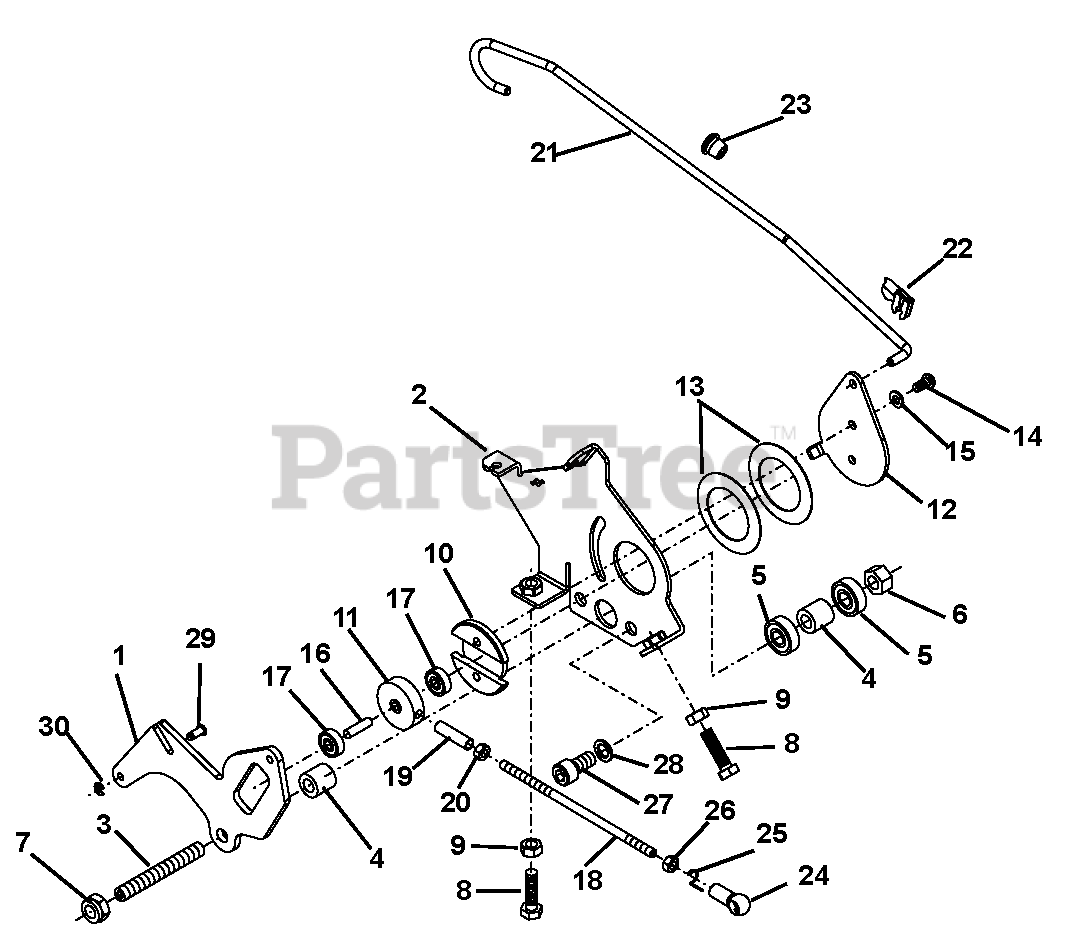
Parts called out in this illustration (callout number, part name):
1	Lever, Forward
2	Bearing Plate
3	Stud, Threaded, D913 M10 x 80
5	Ball Bearing, 6000 2RS
6	Lock Nut, D980V M10
7	Nut, Lock, D985 M10
8	Bolt, Hex, D933 Metric 8 x 30
9	Nut, Hex D934 M8
10	Pivoting Bearing
12	Plate, Pivoting
13	Bell Washer, 31085 40,5 x 61
14	Screw, ISO7380 Metric 6 x 12
15	Washer, M6
16	Pin Cylindrical, D6325 M6 x 24
17	Ball Bearing, 626 2RS
18	Rod, Threaded, M6 x 155
19	Disrtance Spacer, Right 8/0, 75
20	Nut, Hex D934 M6
21	Control Rod
22	Friction Spring, N580 6 SXN-04
24	Pan, Ball, D71805 10B LINKS
25	Bow, Lock, D71805 10S
26	Hex Nut, D934 M6 LI
27	Bolt, Cylindrical, D912 M10
28	Washer, Form Z 10.2/16.1 x 1.6
30	Washer, Lock
